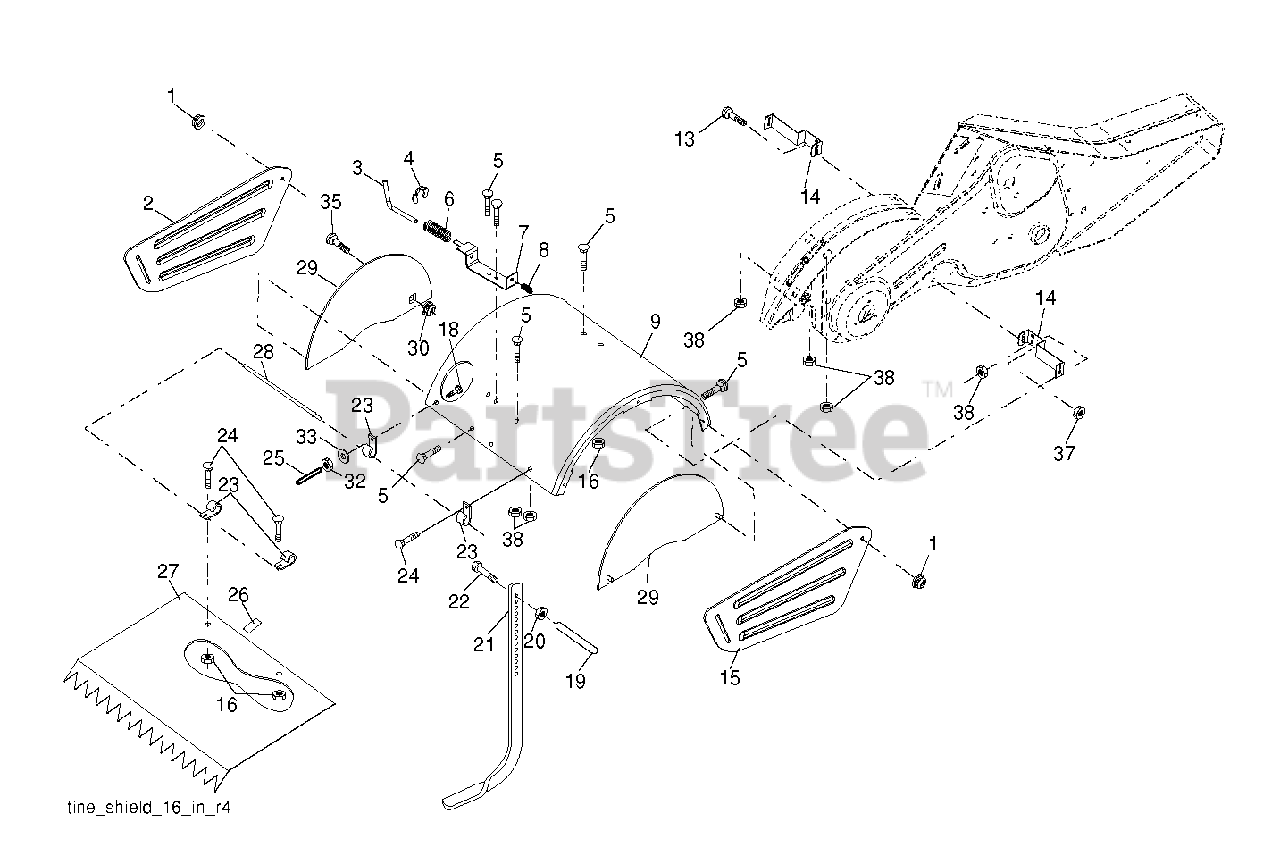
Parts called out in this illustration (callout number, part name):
1	NUT LOCK HEX FLANGE 5/16-18
5	BOLT, RDHD SQNK 5/16-18 X 3/4
7	LATCH BRACKET TI
13	BOLT.CARRIAGE.5/16-18
14	BRACKET.TINE.SHIELD.TILLER
15	SHIELD.SIDE.OUTER.LH.BLACK.GLO
16	NUT T
20	NUT.HEX.3/8-16UNC
21	STAKE DEPTH CRT
25	VINYL CAP TI
28	PIN.HINGE.TILLER
30	LOCKNUT-FLANGE 5/16-18
32	NUT
33	LOCKWASHER
35	BOLT
37	NUT.71038.31-18.HEX.NYLOCK
38	NUT
